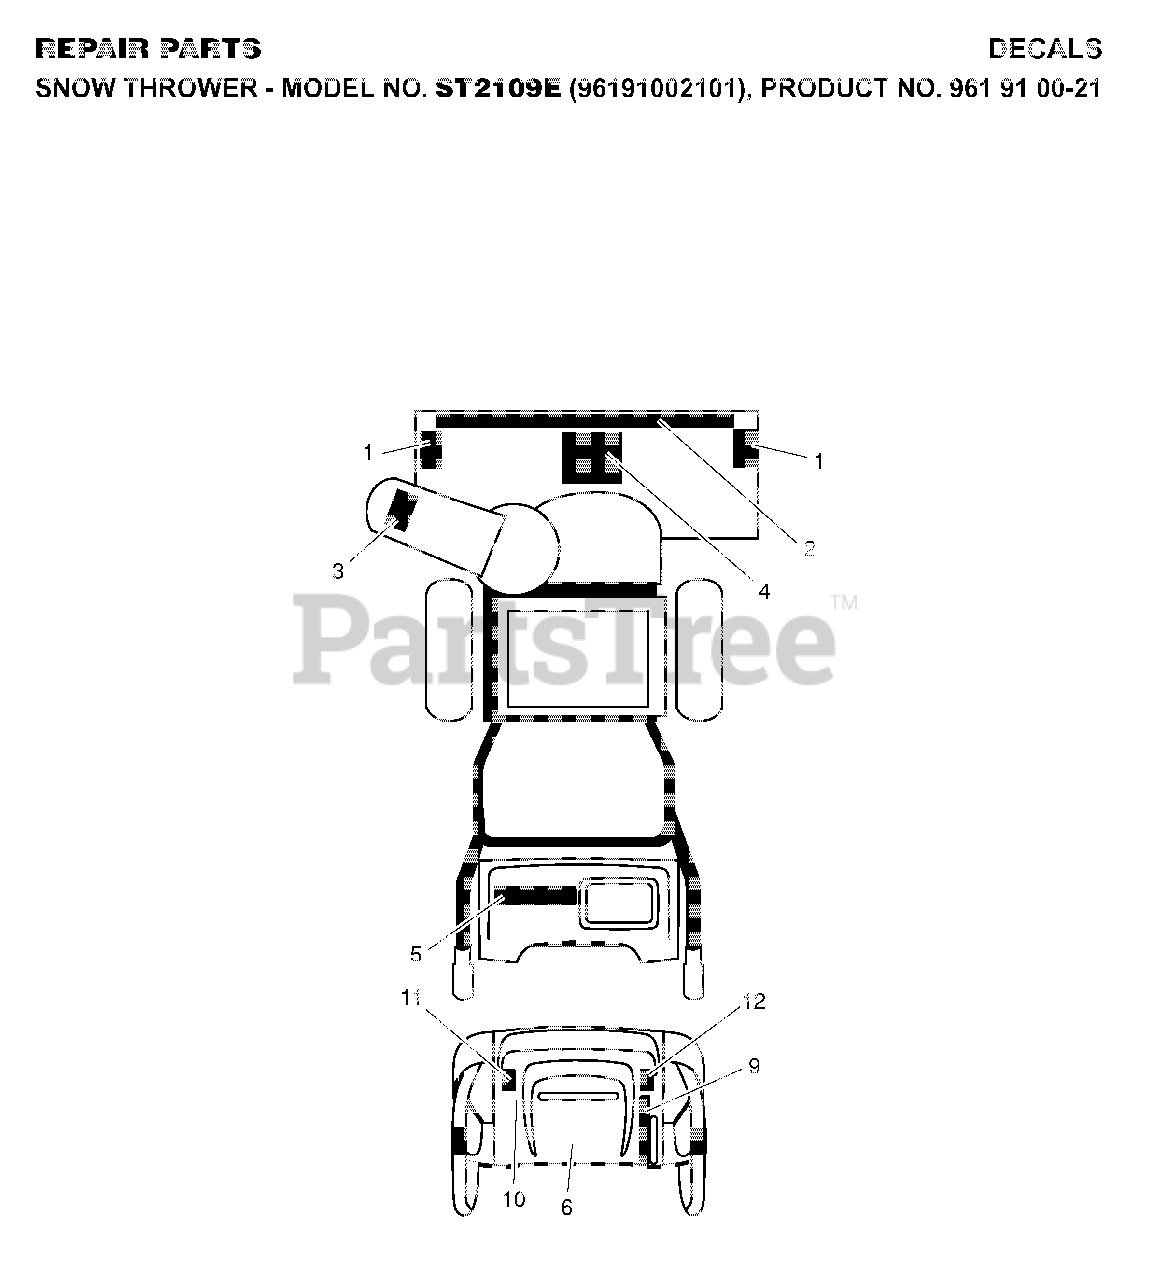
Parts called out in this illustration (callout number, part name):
1	DECAL.AUGER.SAFETY.
3	DECAL.CHUTE.SAFETY.
4	DECAL.AUGER."
6	DECAL.CONSOLE.INSTRUCTION
10	DECAL.REM.DEFLECTOR.LT
11	DECAL.POWER.STEER.LT.TRIG.INT
12	DECAL.POWER.STEER.RT.TRIG.INT
